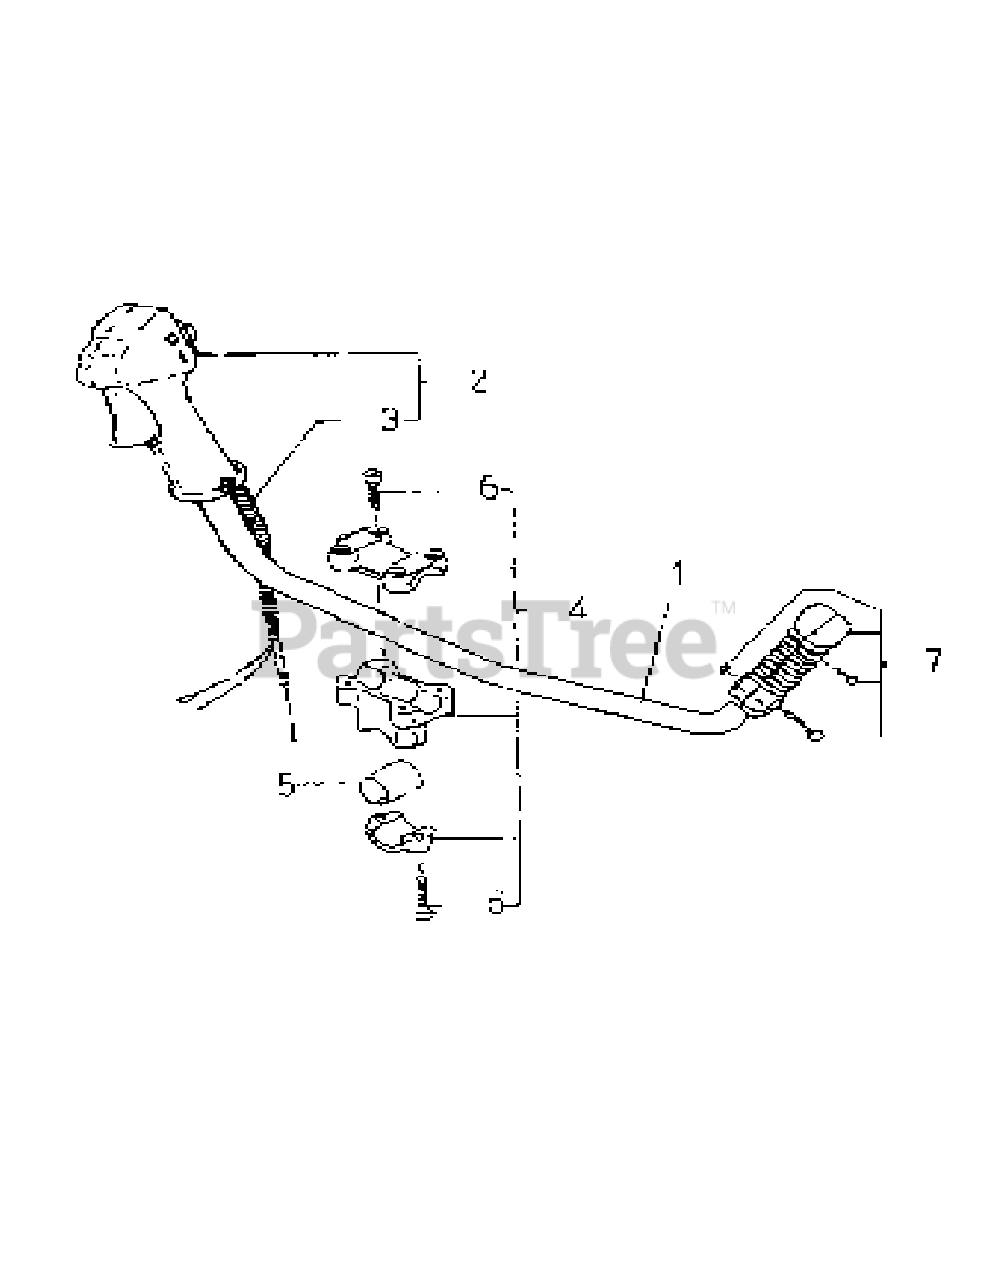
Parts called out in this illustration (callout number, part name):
2	Throttle Lever Assemly
3	Wire, Throttle
4	Holder, Handle
7	Grip Assembly
